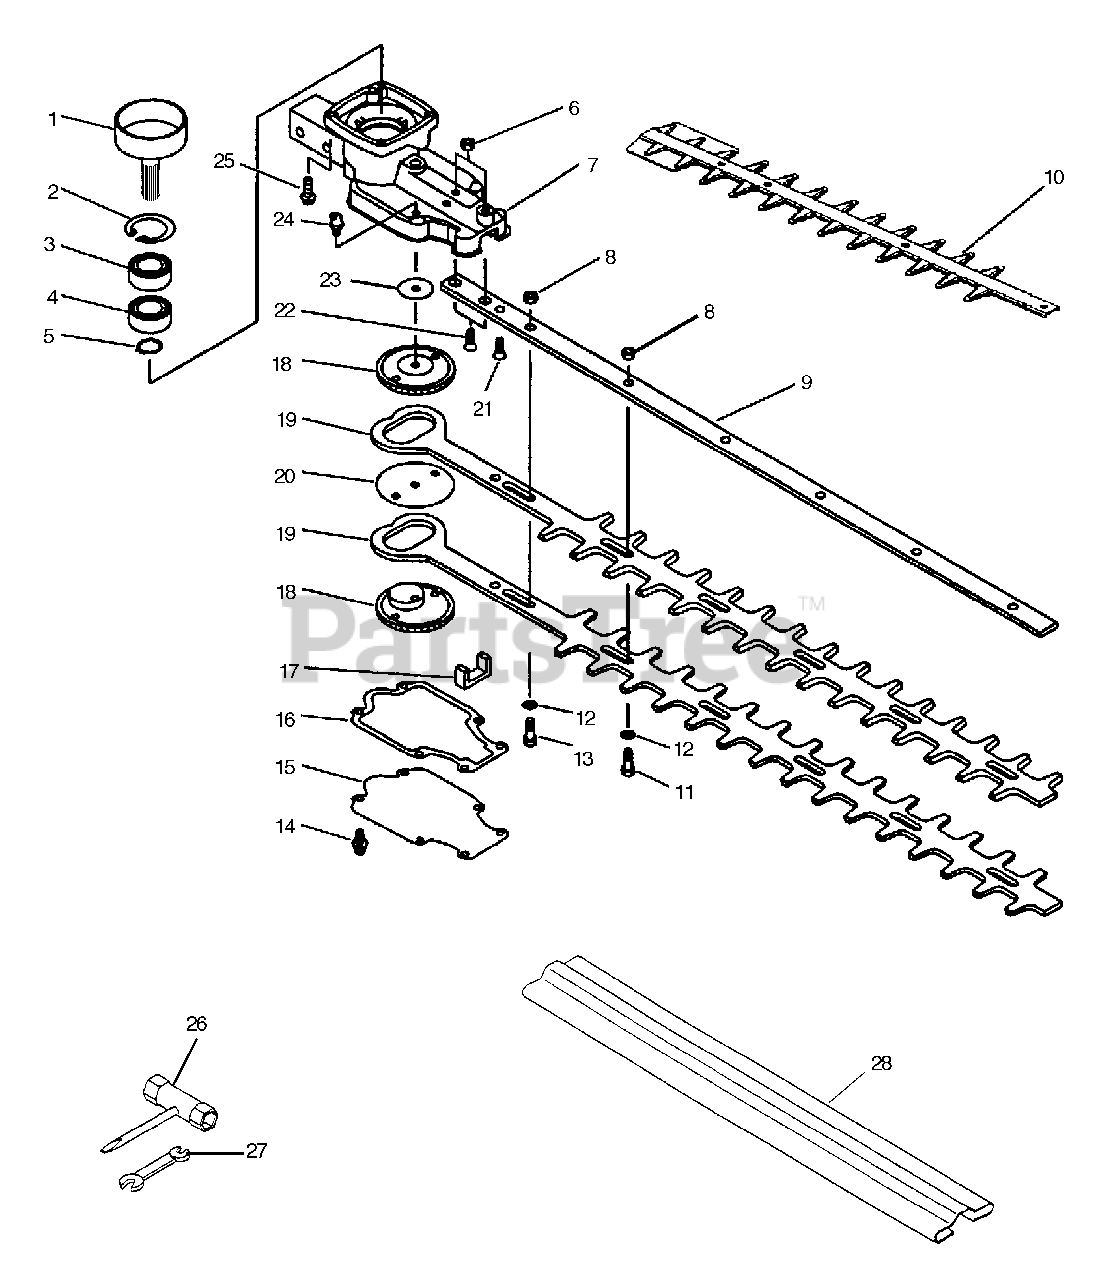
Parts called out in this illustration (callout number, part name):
1	DRUM, CLUTCH
2	RING, SNAP 35
3	BEARING, BALL 6202
4	BEARING, BALL 6202
5	RING, SNAP 14
6	NUT, HEX M6
7	CASE, GEAR
9	SUPPORT, BLADE
10	STIFFENER
12	WASHER 6.5×15.5×0.6
13	BOLT M6×35
14	BOLT 4×12
15	LID, GEAR CASE
16	GASKET, GEAR CASE
18	GEAR, SPUR
19	BLADE, TRIMMER
20	WASHER 6.7×54×0.38
21	SCREW 5×30
22	SCREW 6×30
23	WASHER 6.5×30×0.2
24	FITTING, GREASE
25	BOLT 4×16
26	T-WRENCH 13×19×180
27	SPANNER 8×10
28	COVER, BLADE
